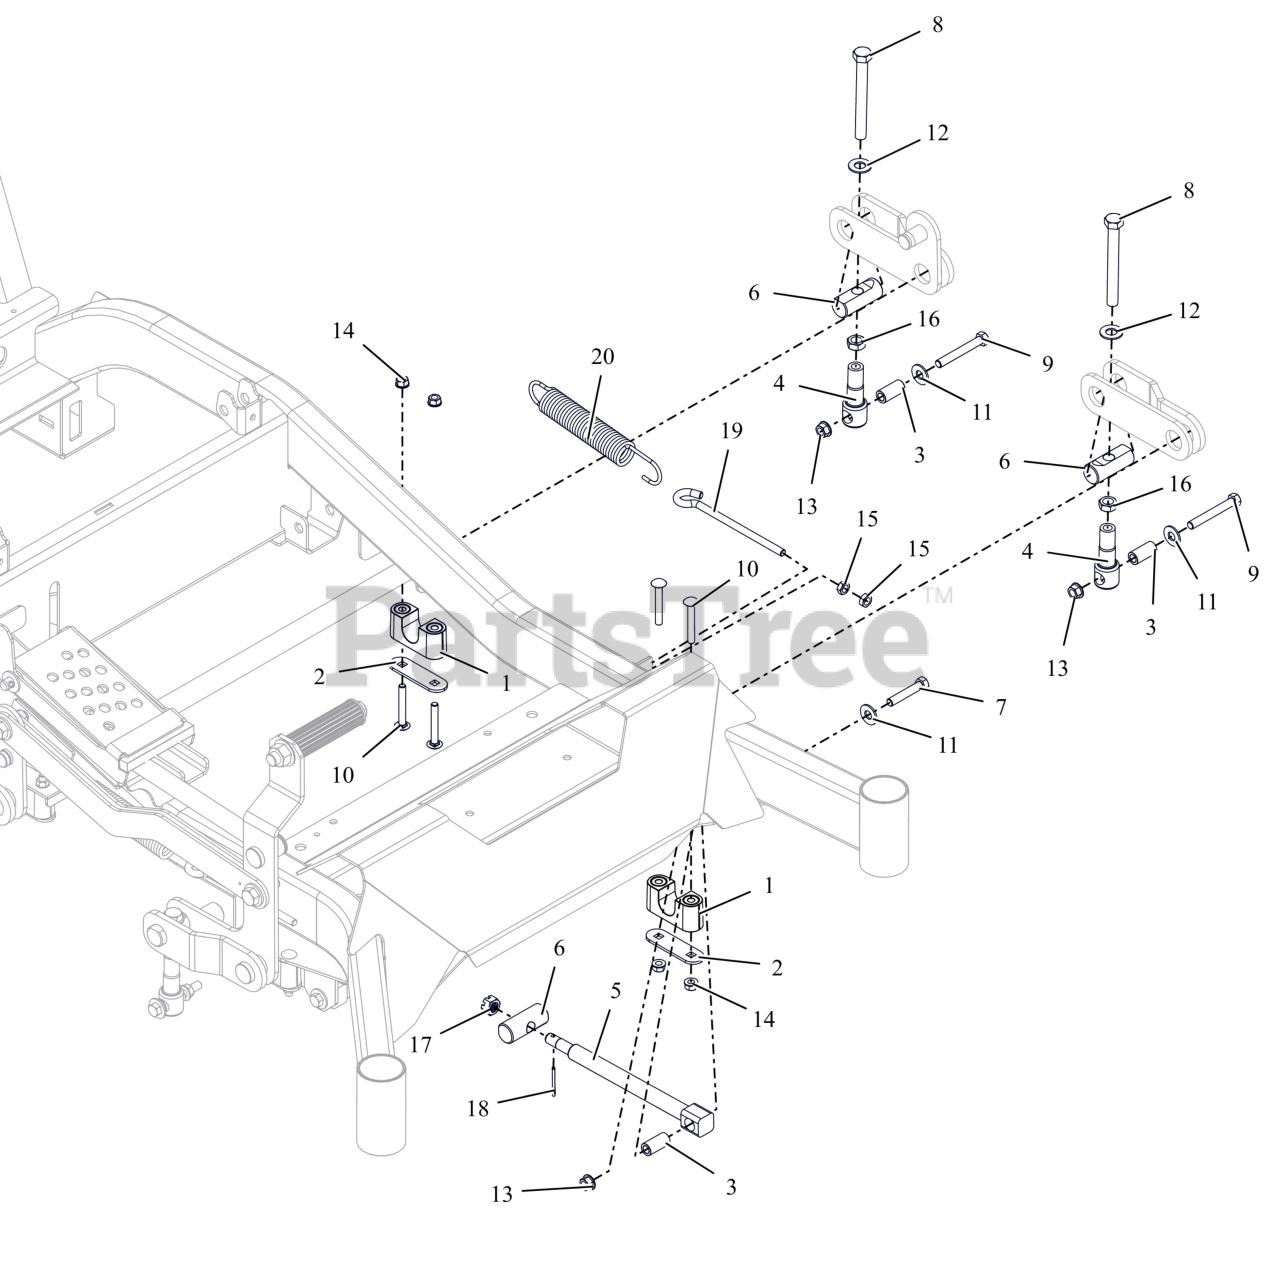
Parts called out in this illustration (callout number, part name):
1	ASM-BUSHING, DECK LIFT
2	PLATE, BEARING SUPPORT
3	SPACER, DECK LEVELING
4	LINK, DECK LIFT FORMED
5	DRAG,LINK-HD
6	PIN, DECK LIFT
7	BLT,HEX .38-16X2.00 G5 ZCC
8	BLT, HEX .50-13X4.50F G8 ZCC
9	BLT, HEX .38-16X2.75 G8 ZCC
10	BLT, RHSSN.31-18X2.25 G5 ZCC
11	WSHR,FLT .438X1.00X.083 ZCC
12	WSHR, FLT .557X1.040X.102 ZCC
13	NUT-LK-TOP-FLG .38-16 ZC120
14	NUT,LK-CTR-FLG .31-18 GF ZCC
15	NUT-JAM .375-16 G2 ZCC
16	NUT-JAM .500-13 G2 ZCC
17	NUT-SL .50-13
18	PIN,CTR.12X1.25EXTPRSQCT ZC120
19	BOLT,.38-16 X 5.25-.62 DIA EYE
20	SG-TENS .162X1.25X8.25 WLD 25
